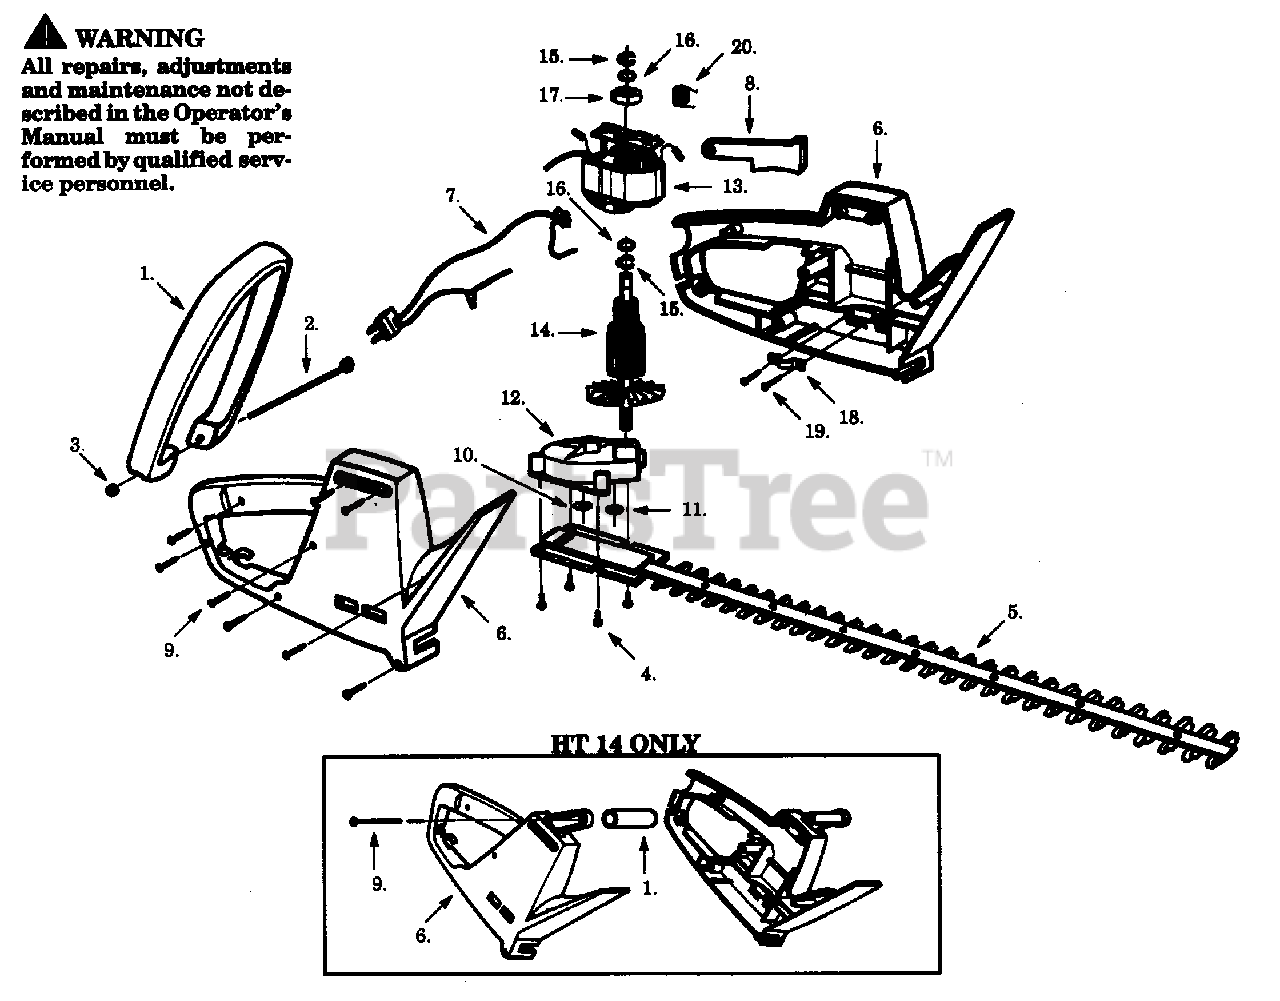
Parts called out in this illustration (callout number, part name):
1	MODEL HT14
1	MODELS HT17, HT19, HT22
2	Screw-Handle
3	Locknut-Handle
4	Screw-Blade
5	Blade Ass'y. - 14"
5	Blade Ass'y. - 17"
5	Blade Ass'y. - 19"
5	Blade Ass'y. - 22"
6	MODEL HT14
7	Switch/Plug Ass'y.
8	Trigger Switch
9	Screw-Housing
11	Drive Washer
13	Field Ass'y.
14	Armature Ass'y.
15	Retaining Ring
20	Spring-Brush
